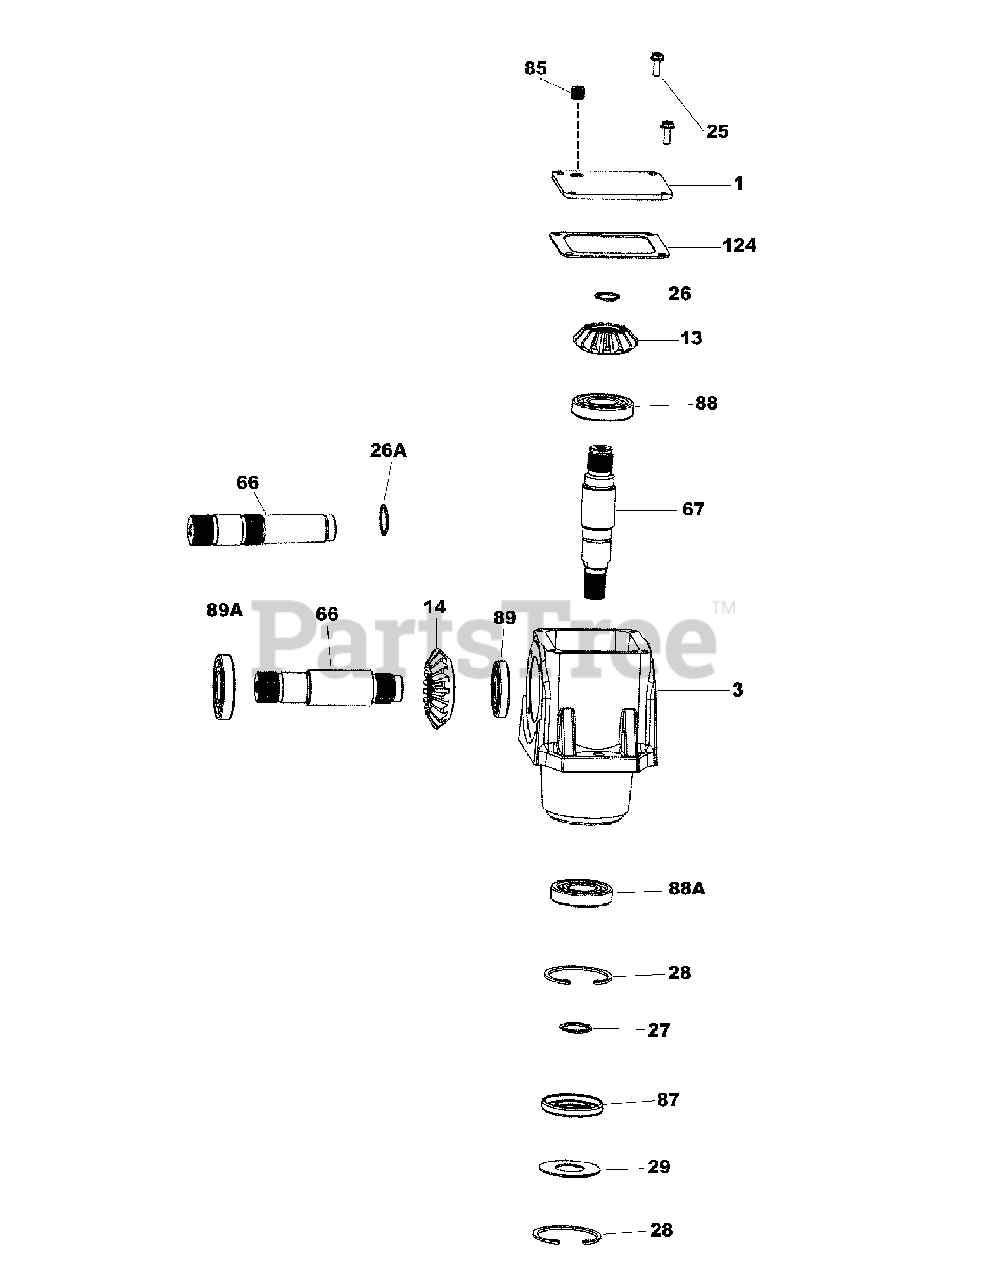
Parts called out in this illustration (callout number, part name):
3	Case (cast-iron)
13	Bevel Gear 17T STL
14	Bevel Gear 17T STL
25	Screw, 10-24 x 1/2"
27	Retaining Ring .812 X .042 INT
27	Retaining Ring .984 X .042 EXT
66	Input Shaft
67	Output Shaft
85	Pipe Plug 1/8-27
87	Oil Seal 1.125 ID
87A	Oil Seal .875 ID
88	Ball Bearing .9838 ID
88A	Ball Bearing .9838 ID
89	Ball Bearing .7495 ID
89A	Ball Bearing .8745 ID
102	Cap & Seal (Incl. 87A & 103)
103	Screw, 1/4-20 x 7/8"
124	Gasket (Cover)
124A	Gasket (Cap)
